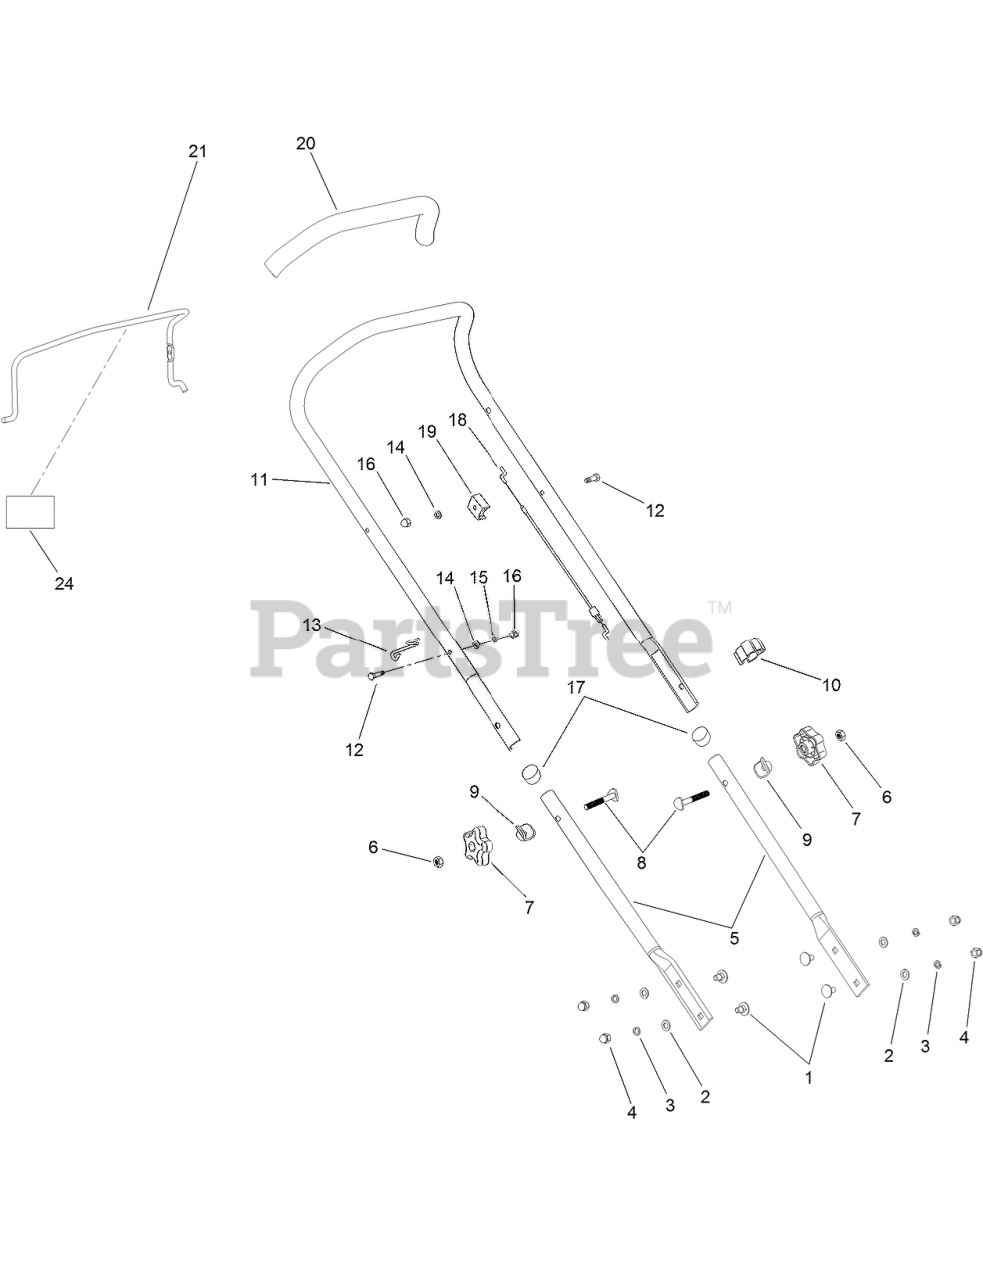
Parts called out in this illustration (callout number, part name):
2	WASHER
3	WASHER-SPRING
4	NUT-LID
5	RAIL-GRAB, LOWER
6	NUT-HEX
7	KNOB-ROTARY, LOWER RAIL
8	BOLT-FLAT HEAD
9	WASHER-CURVE
10	CABLE CLAMP
11	RAIL-GRAB, UPPER
12	BOLT-HH, FLANGE
13	HOOK-CABLE
14	WASHER-PLAIN
15	WASHER-SPRING
16	NUT-LID
17	PLUG-TUBE
18	FRAMEOUT CORD ASM
19	CABLE-BLOCK, FIXED
20	GRIP-HANDLE
21	ROD-FRAMEOUT
24	DECAL-STOP
